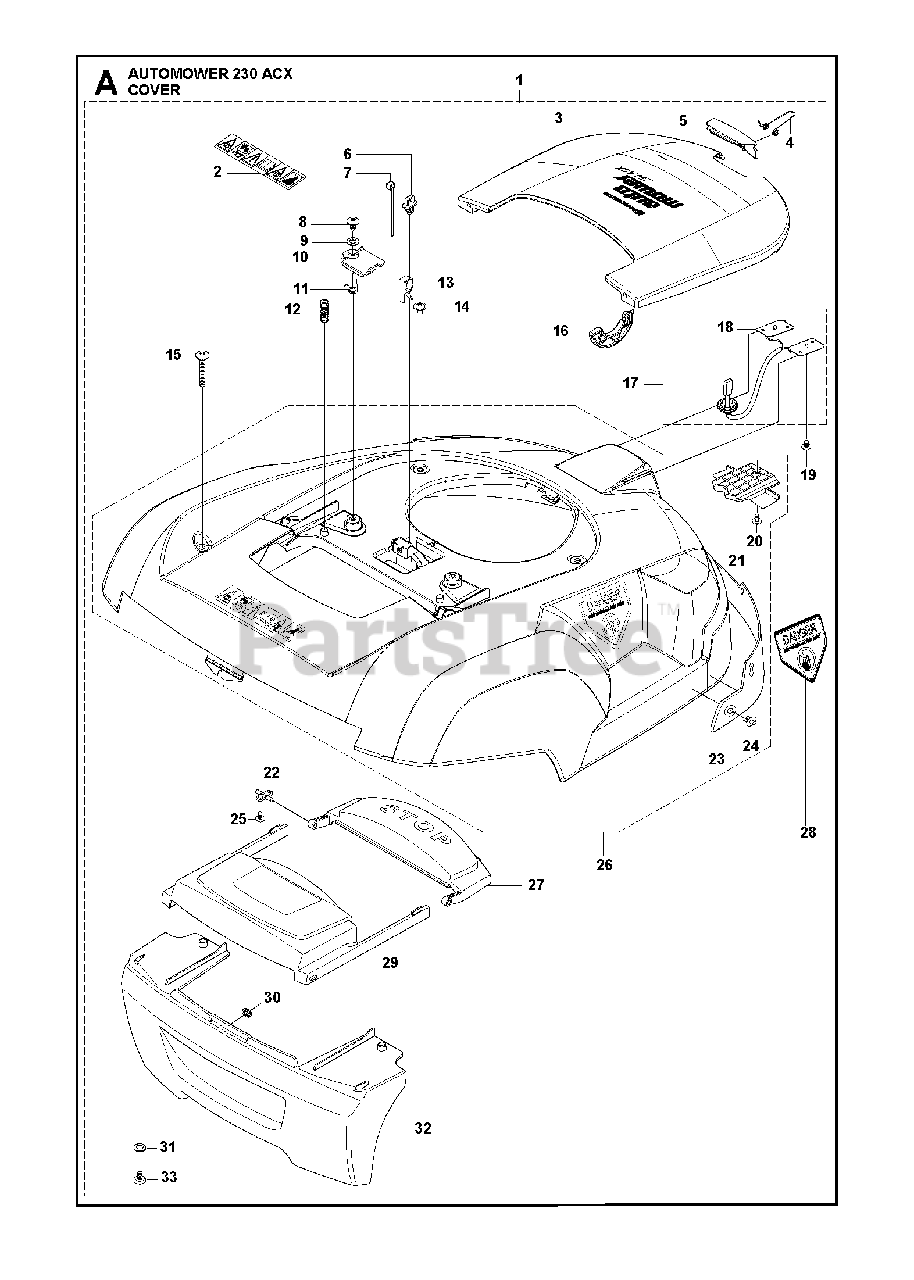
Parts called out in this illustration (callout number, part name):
2	LABEL WARNING
3	COVER 230 ACX
5	HEIGHT ADJ. COVER LATCH
6	BRACKET FOR BAND
8	SCREW SILVER 10MM
13	CLIP RETAINER
15	SCREW IHPANM
17	CABLE ASSY
18	THIN PLATE
19	SCREW WHITE 6MM
20	SCREW 12MM
21	SPACER
24	RIVET
25	SCREW SILVER 10MM
26	MAIN BODY KIT 230 ACX
28	LABEL, DANGER
32	BUMPER, COVER
33	SCREW 14MM
